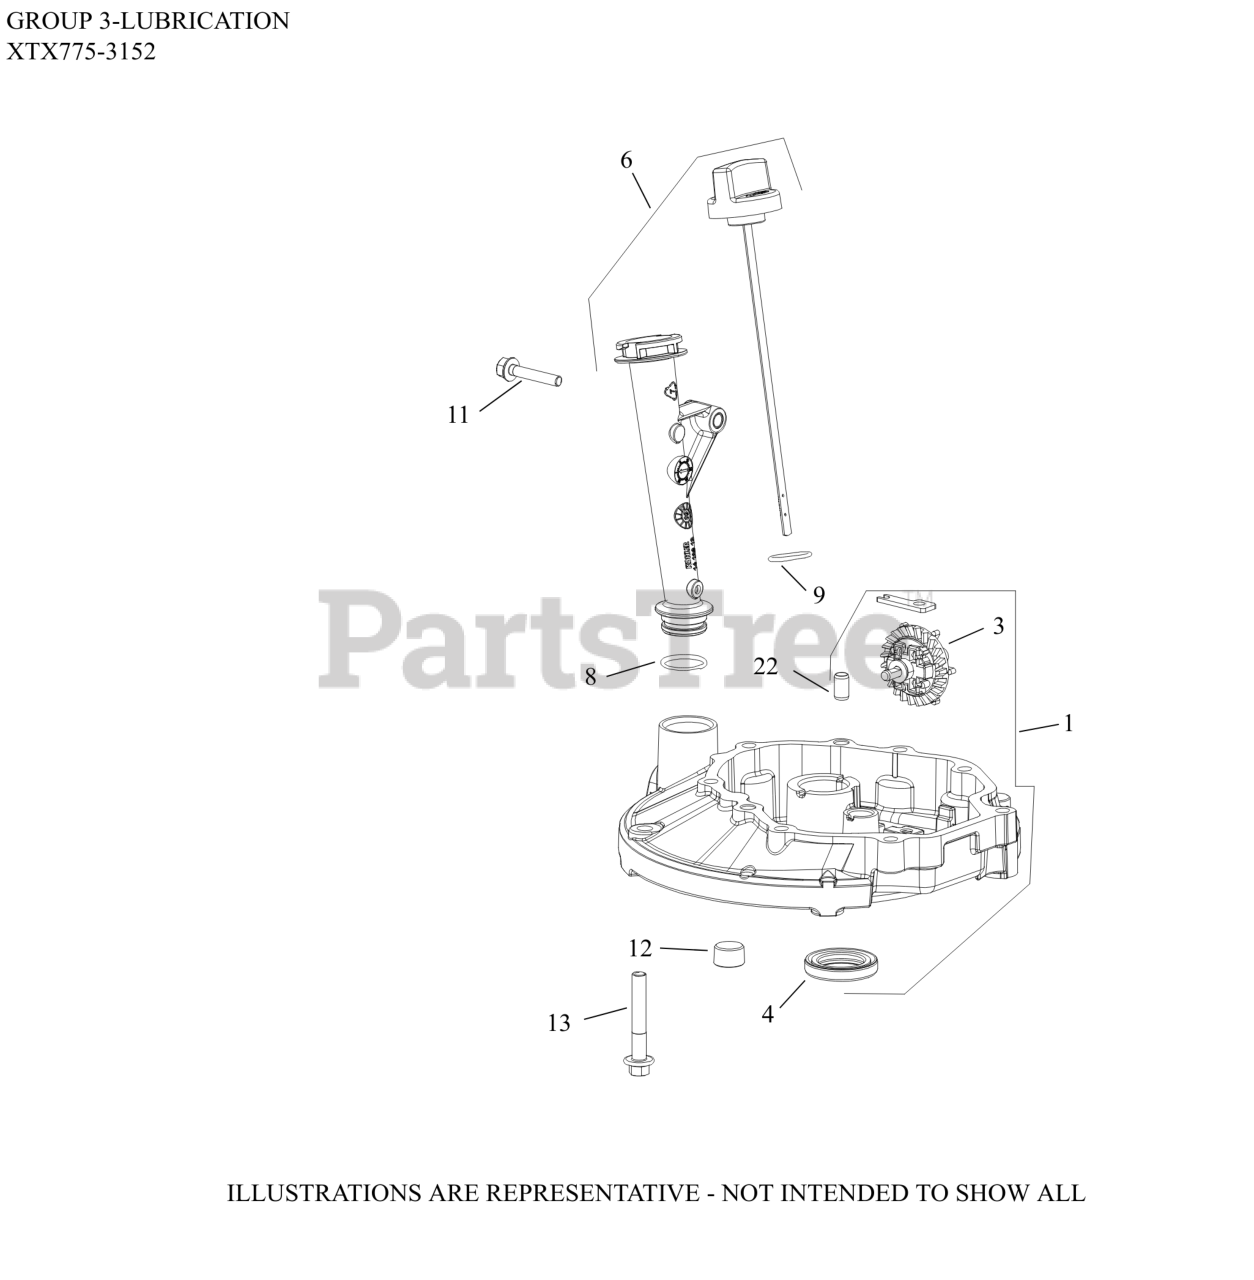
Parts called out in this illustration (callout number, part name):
1	KIT, OIL PAN
3	GEAR ASSEMBLY, GOVERNOR
6	TUBE ASSEMBLY OIL FILL
8	O-RING, OIL FILL TUBE
9	O-RING (CAP)
11	SCREW, HEX FLANGE (M6)-(#25086435S)
12	PLUG, PIPE (W/SEALANT)
13	SCREW, HEX FLANGE (M8)-USE 25 086 456-S
22	PIN, DOWEL (8mm)
